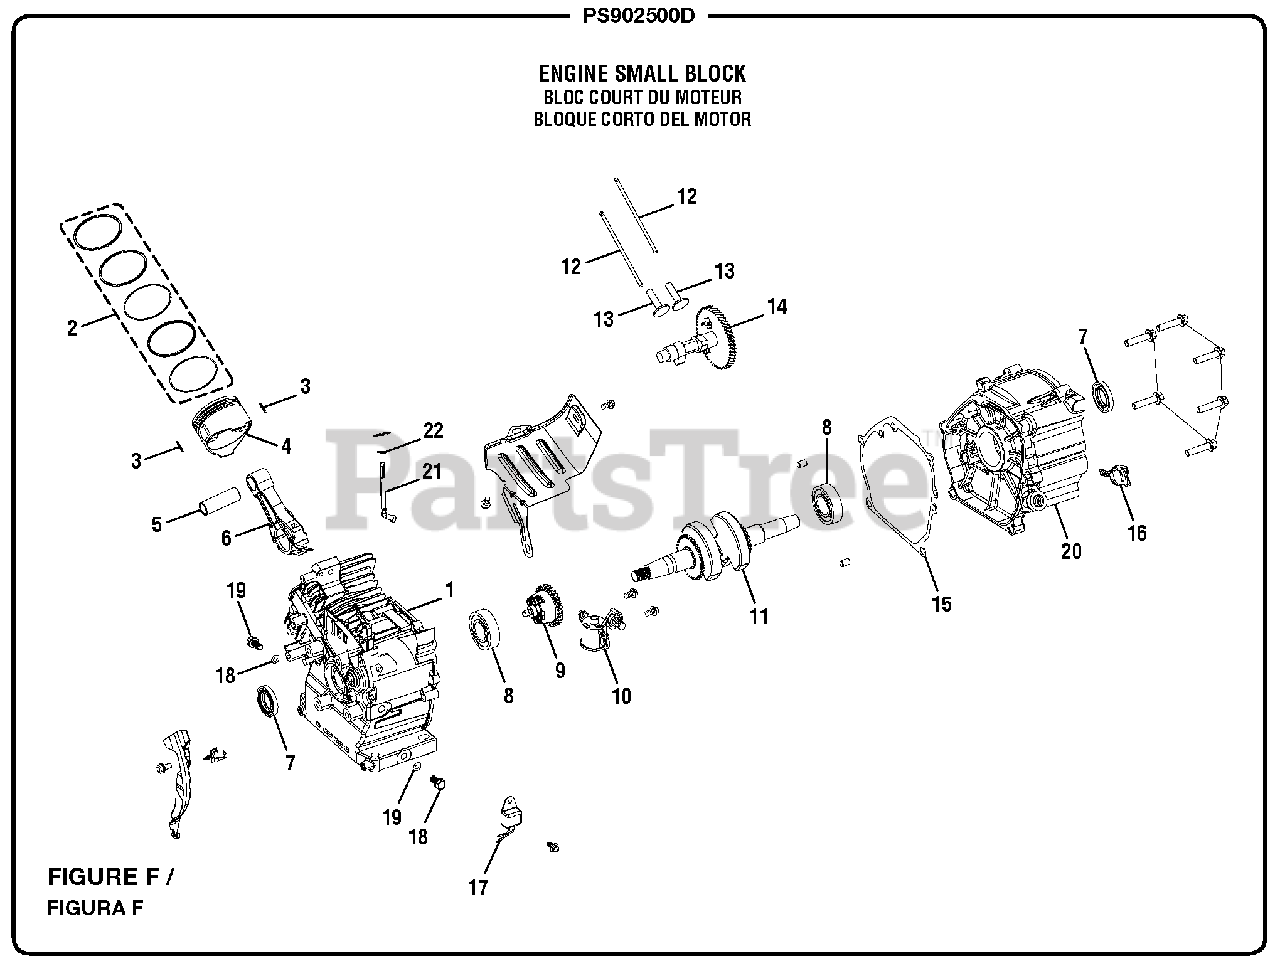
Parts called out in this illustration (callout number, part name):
2	Piston Ring Set
3	Piston Clip
6	Connecting Rod Assembly
8	Ball Bearing
9	Governor Assembly
10	Switch Assembly (Oil Level)
11	Crankshaft Assembly
12	Valve Lifter Assembly
13	Valve Tappet
14	Camshaft Assembly
15	Casecover Gasket
17	Amplifier
20	Crankcase Cover
21	Governor Arm
